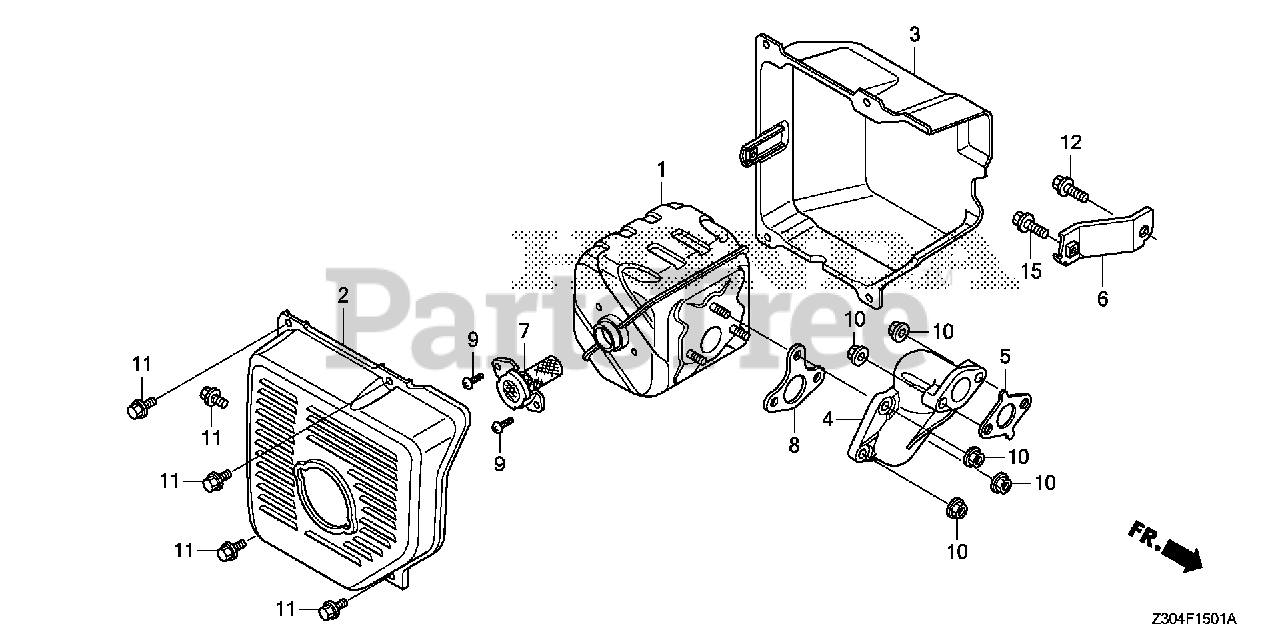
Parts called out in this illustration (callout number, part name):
2	PROTECTOR, MUFFLER (OUTER) *NH105* (MAT BLACK)
3	PROTECTOR, MUFFLER (INNER) *NH105* (MAT BLACK)
5	GASKET, EX. PIPE
6	STAY, MUFFLER
7	ARRESTER, SPARK
8	GASKET, MUFFLER (NIPPON LEAKLESS)
9	SCREW, TAPPING (5X8)
10	NUT, FLANGE (8MM)
11	BOLT, FLANGE (6X10)
12	BOLT, FLANGE (8X16)
15	BOLT, FLANGE (8X22)
